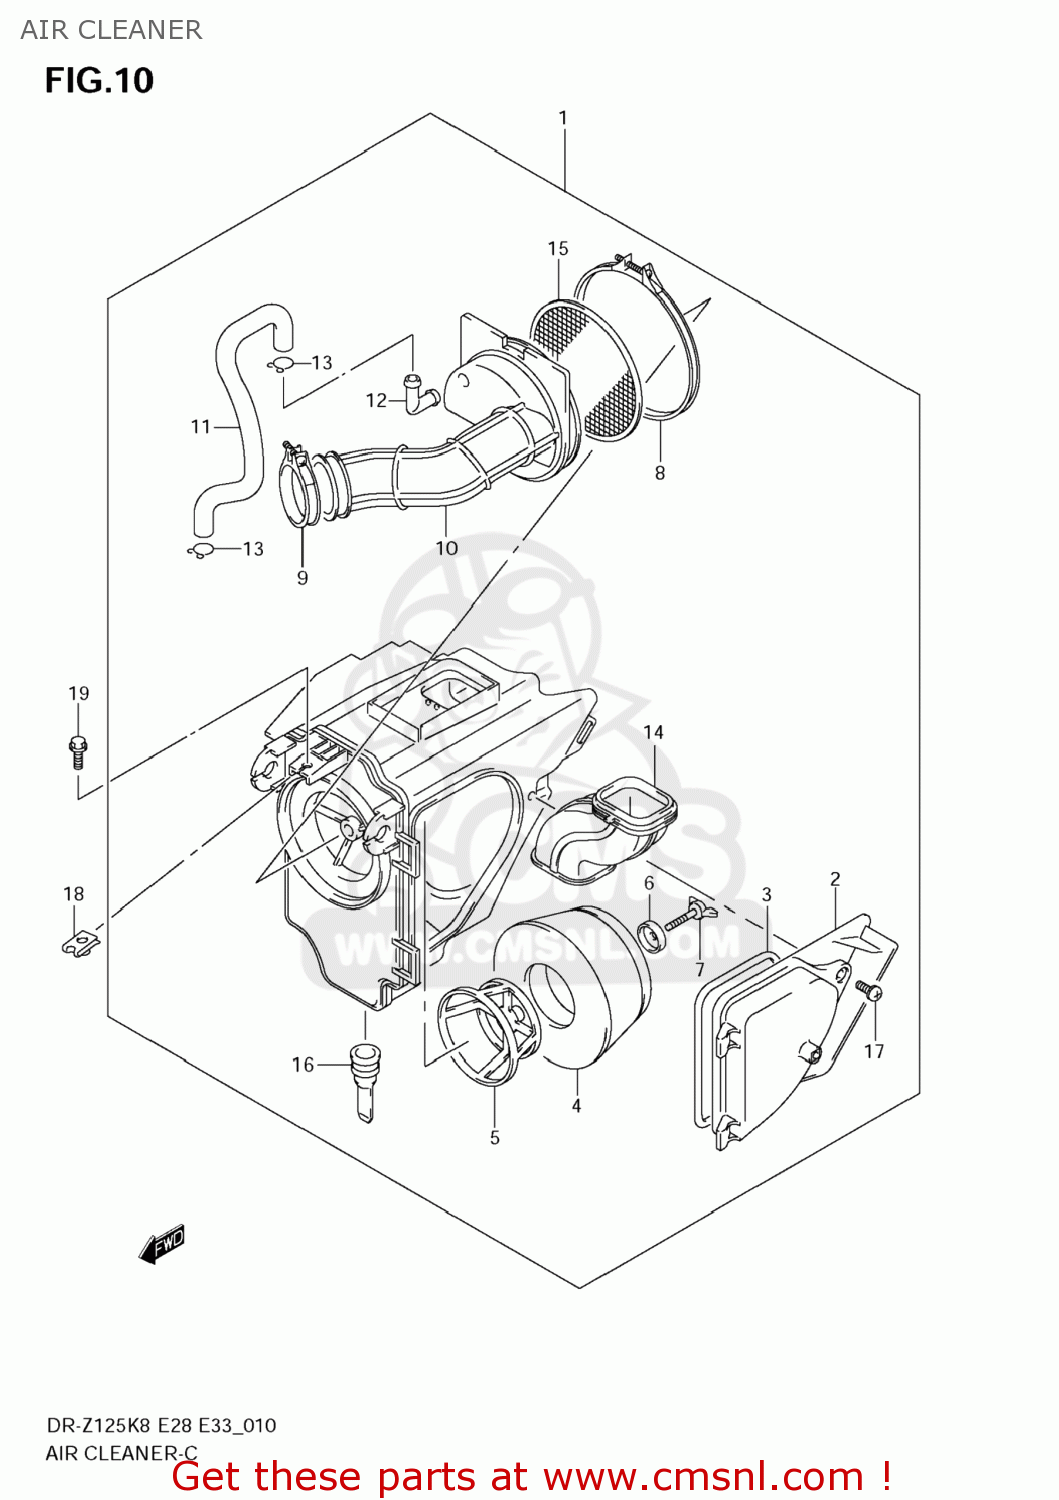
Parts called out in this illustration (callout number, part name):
1	CLEANER ASSY,AIR
2	CAP,AIR CLEANER
3	GASKET (NAS)
4	FILTER
5	HOLDER,FILTER
6	WASHER,AIR CLEANER
7	BOLT, WING
8	CLAMP,OUTLET TUBE
9	CLAMP
10	TUBE,OUTLET
11	TUBE,BREATHER
12	JOINT
13	CLIP
14	TUBE,INLET
15	TRAP,FLAME
16	CAP,DRAIN
17	SCREW
18	NUT
19	BOLT
